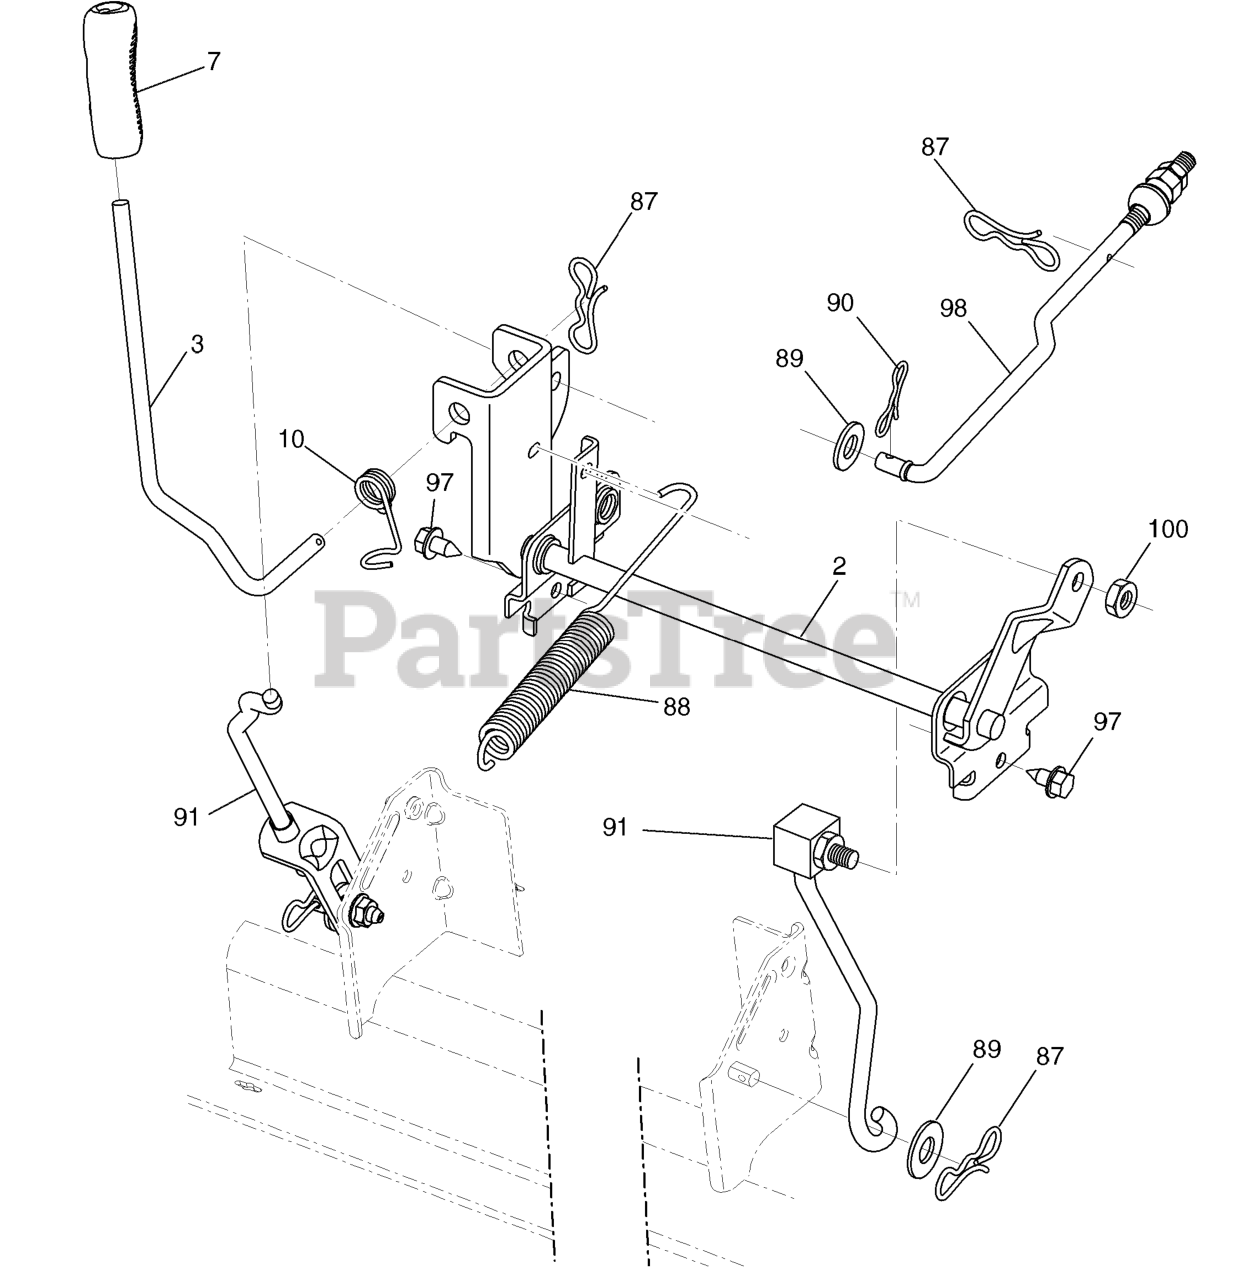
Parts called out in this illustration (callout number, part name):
2	SHAFT.ASM.LIFT.CROSS.H
3	LEVER.LIFT.HANDLE.GT
7	GRIP.HANDLE.LIFT.PVC.BLACK
10	SPRING.TORSION.LIFT.HANDLE
87	PIN.COTTER.7/16.BOW TI.
88	SPRING.LIFT.ASSIST
89	WASHER.CLEAR.ZINC
90	PIN.COTTER.5/16.BOW TI
91	LINK.ASM.LIFT.REAR
97	SCREW, 3/8-16X3/4
98	LINK.ASM.SUSP.FRONT.MW
100	LOCKNUT
